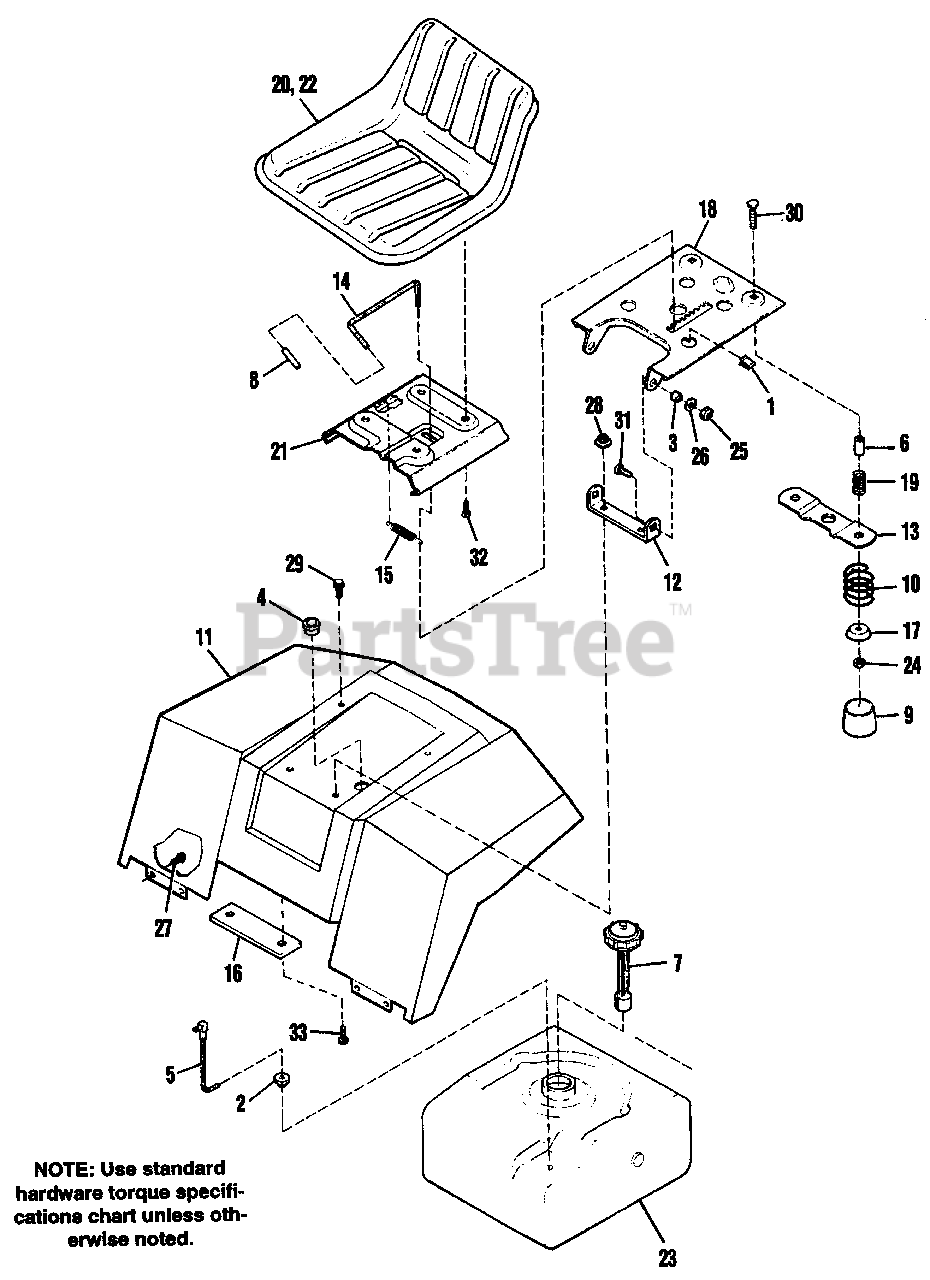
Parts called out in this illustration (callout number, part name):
1	CLIP, Speed
4	BUSHING, Snap
5	ELBOW & TUBE ASSY.
7	CAP, Fuel Gauge
8	HANDLE, Grip
9	COVER, Spring
10	SPRING, Compression, 2" O.D.
11	SEAT DECK (Orange)
11	SEAT DECK (Red)
12	BRACKET, Seat, Pivot
13	PLATE, Switch
14	LEVER, Seat Release
16	PLATE, Reinforcement
17	WASHER, Plain
18	SUPPORT, Seat, Pivot
19	SPRING, Compression
20	SEAT (Incl. Ref. No. 22)
21	BRACKET, Seat Slide
22	COVER, Seat
24	NUT, Hex, Full, 5/16-18
25	NUT, Hex Hd., Nyloc, 3/8-16
26	WASHER, Plain, 13/32
27	SCREW, Taptite, 1/4-20 x 1/2
28	NUT, Hex, Flange, Whizlock, 3/8-16
29	SCREW, Taptite, 5/16-18 x 5/8
30	CARRIAGE BOLT, 5/16-18 x 2
31	CARRIAGE BOLT, 3/8-16 x 1
32	BOLT, Hex, Whizlock, 5/16-18 x 5/8
33	SCREW, Truss Hd., Torx Dr., 3/8-16 x 1
